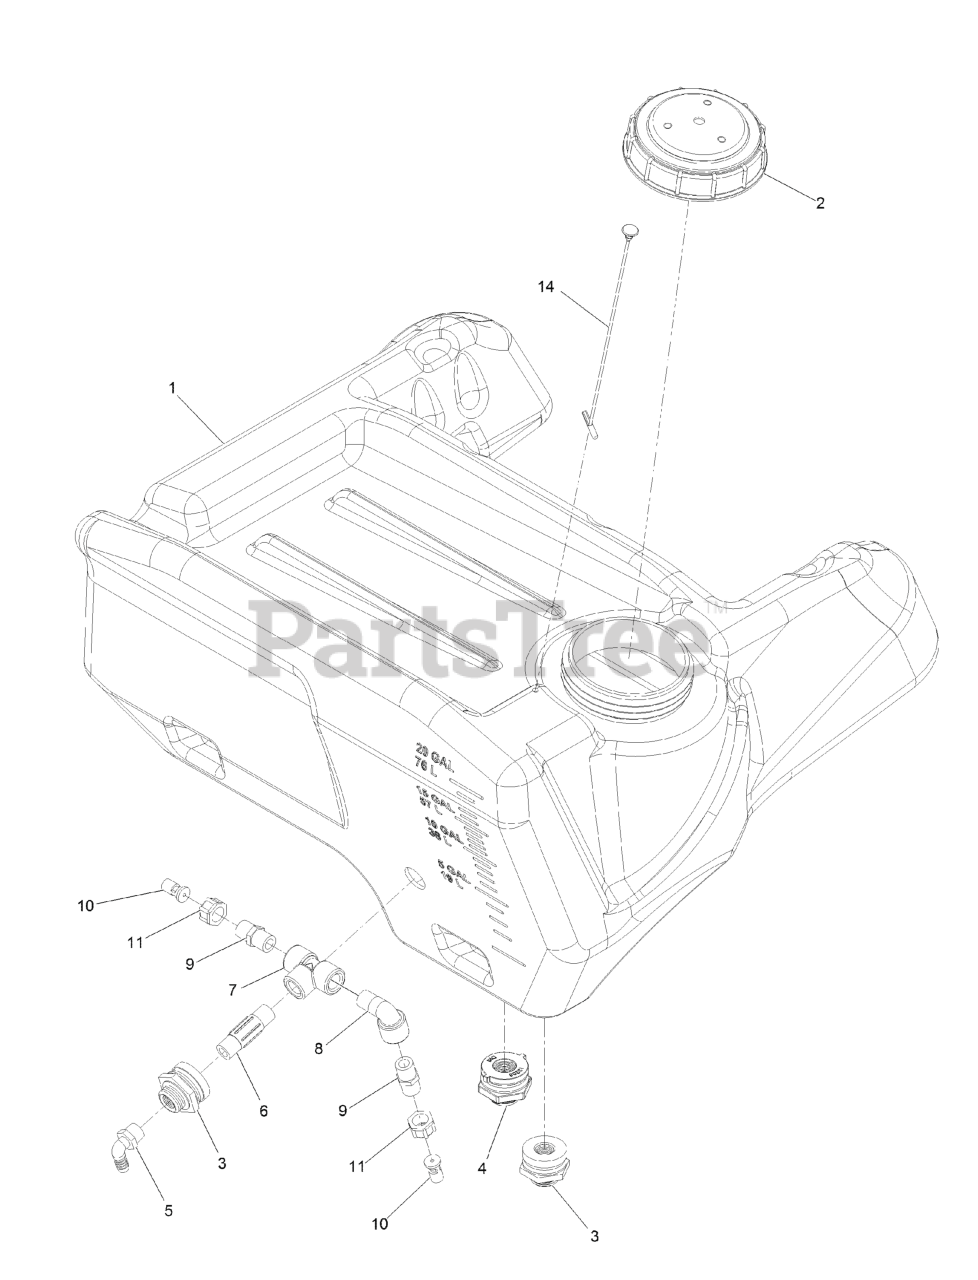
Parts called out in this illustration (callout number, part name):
1	Tank-Sprayer
2	CAP-WATER, 5 INCH VENT
3	FITTING-BULKHEAD
4	FITTING-BULKHEAD
5	ELBOW-90 DEG
8	ELBOW-90 DEG
9	NIPPLE-SHORT
10	NOZZLE-AGITATION
14	LANYARD-CAP, SELF ANCHORI
